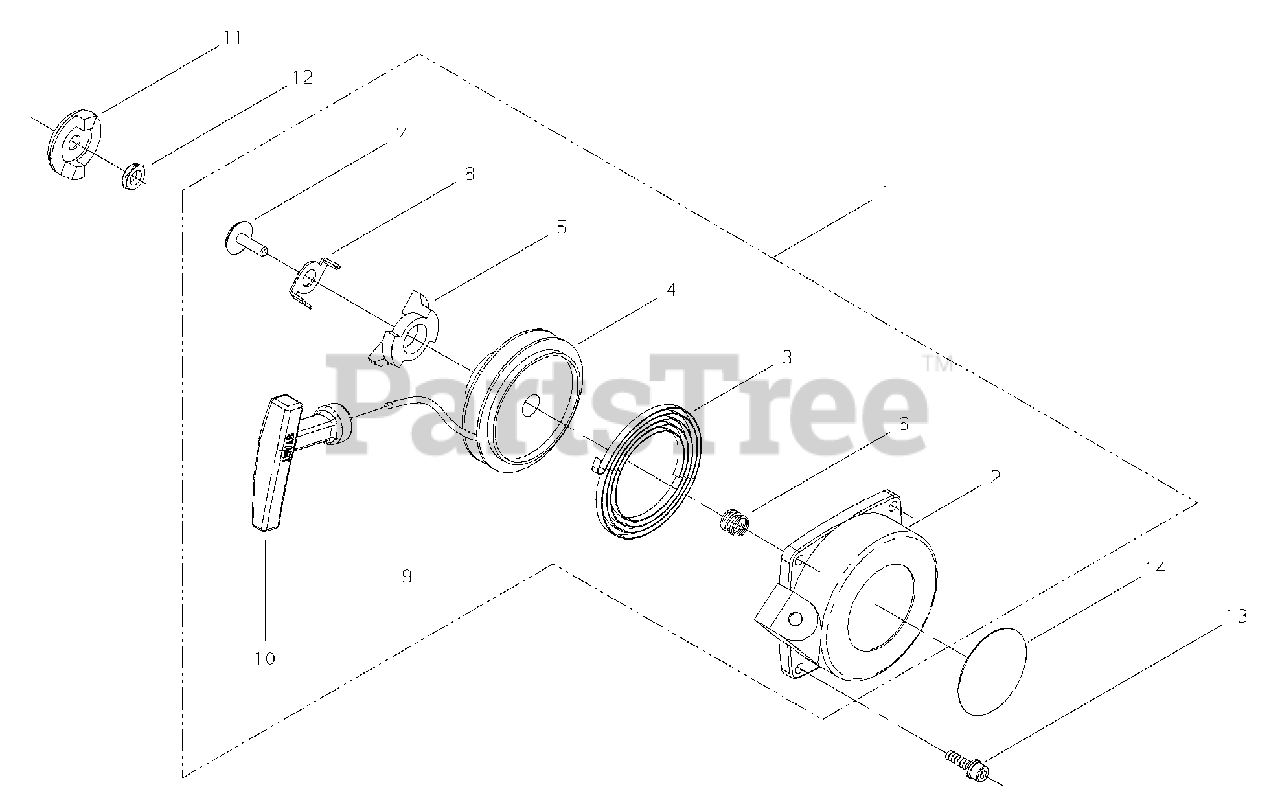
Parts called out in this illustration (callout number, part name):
1	STARTER ASSY
2	CASE, STARTER
3	SPRING, REWIND
4	REEL, ROPE
5	PAWL, STARTER
6	SPRING, BRAKE
7	SCREW
8	RETAINER
9	ROPE, STARTER
10	GRIP, STARTER
11	REEL, ROPE
12	NUT - 8
13	SCREW - 5X20
14	LABEL - C4
